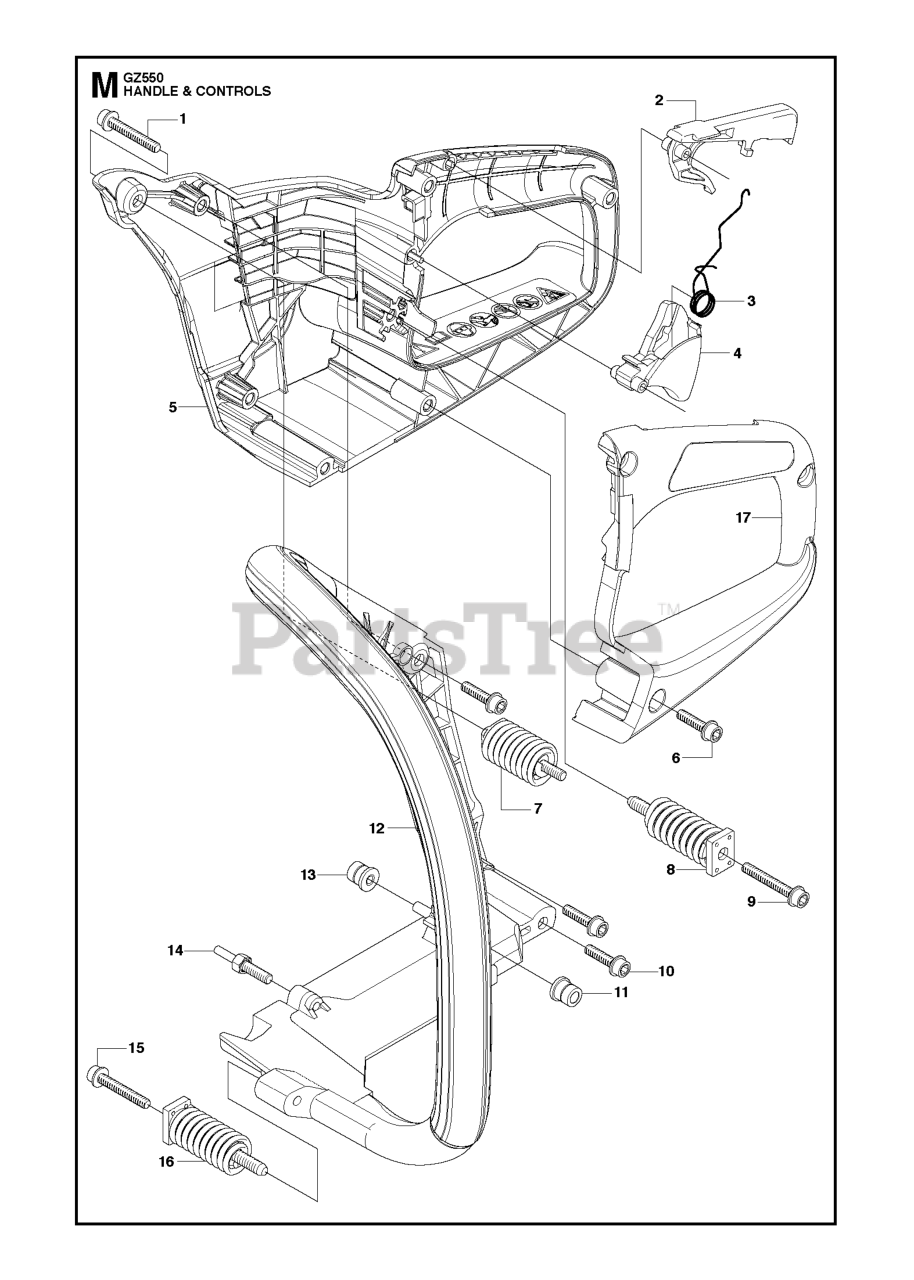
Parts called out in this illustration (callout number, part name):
2	THROTTLE LOCKOUT
3	RECOIL SPRING
4	THROTTLE TRIGGER
5	REAR HANDLE
7	VIBRATIONS ABSORBER
8	ANTI-VIBRATION ELEMENT
11	MOVEMENT LIMITER
12	FRONT HANDLE
13	MOVEMENT LIMITER
